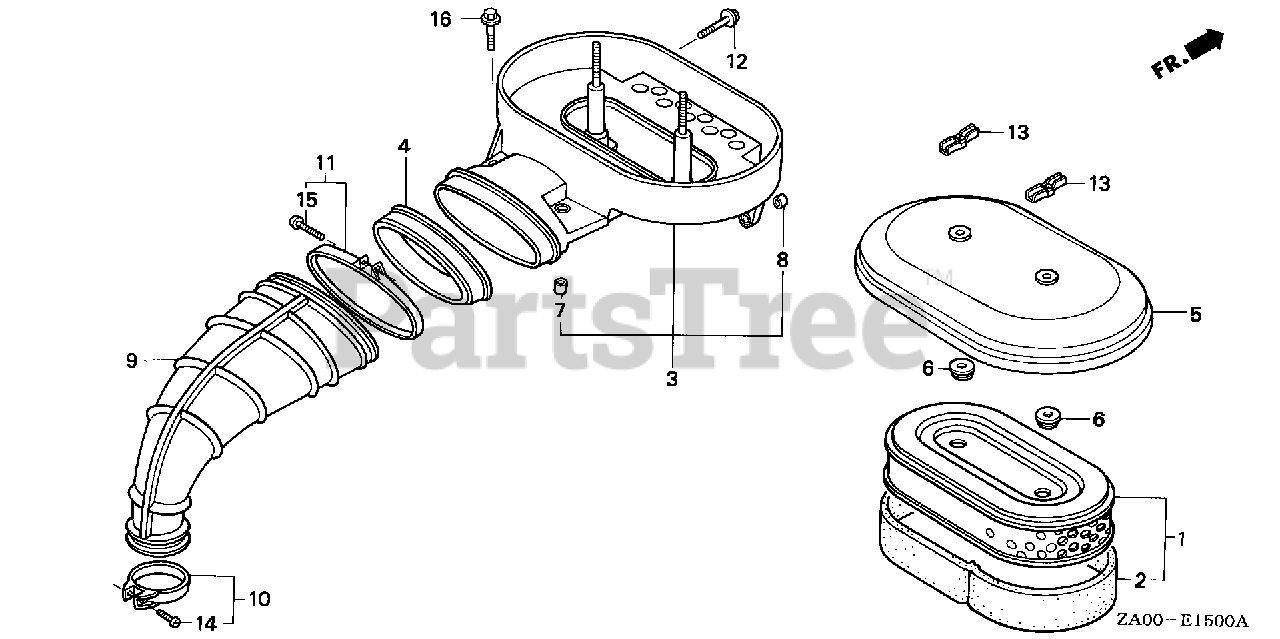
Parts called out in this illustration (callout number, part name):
1	ELEMENT, AIR CLEANER (DUAL)
1	ELEMENT, AIR CLEANER
2	FILTER (OUTER)
3	HOUSING, AIR CLEANER
4	SUPPORTER, AIR CLEANER
5	COVER, AIR CLEANER
6	GROMMET, AIR CLEANER
7	COLLAR A, AIR CLEANER
8	COLLAR B, AIR CLEANER
9	TUBE, AIR CLEANER CONNECTING
10	BAND, CONNECTING TUBE
11	BAND ASSY., CONNECTING TUBE
12	BOLT, FLANGE (6X25) Use up to Engine SN 2056819.
13	WINGNUT, AIR CLEANER COVER
14	SCREW, PAN (4X26)
15	SCREW, PAN (4X25)
16	BOLT, FLANGE (6X35)
